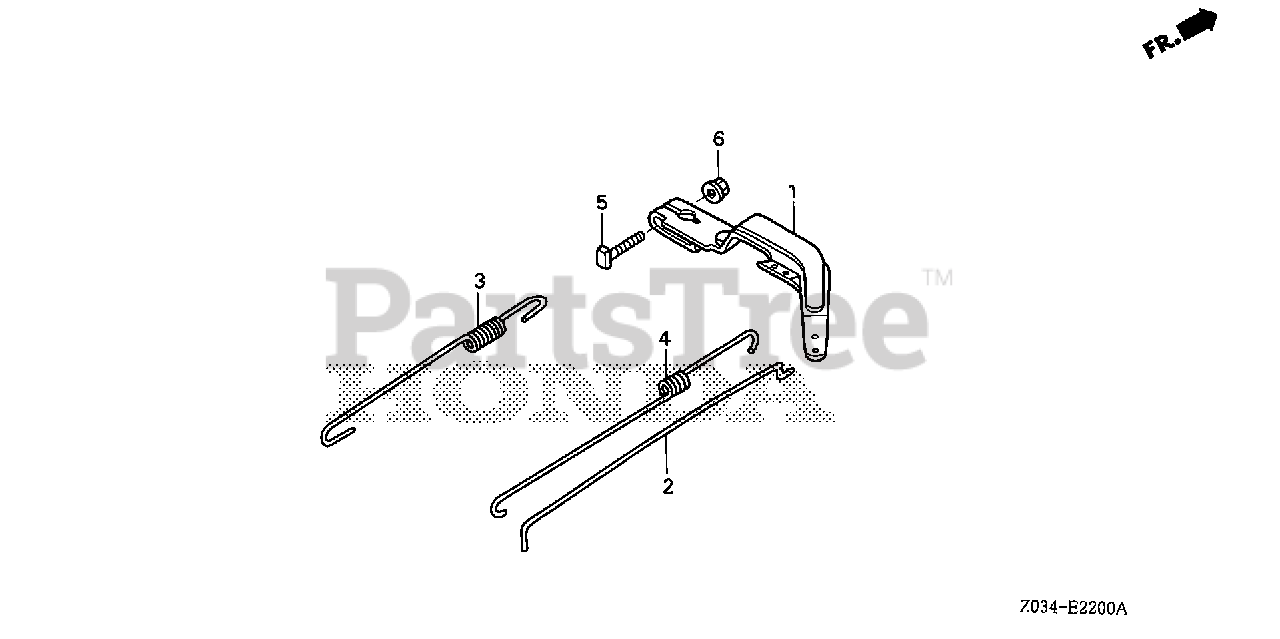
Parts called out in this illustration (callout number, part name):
1	ARM, GOVERNOR
2	ROD, GOVERNOR
3	SPRING, GOVERNOR
4	SPRING, THROTTLE RETURN
5	BOLT, GOVERNOR ARM
6	NUT, FLANGE (6MM)
